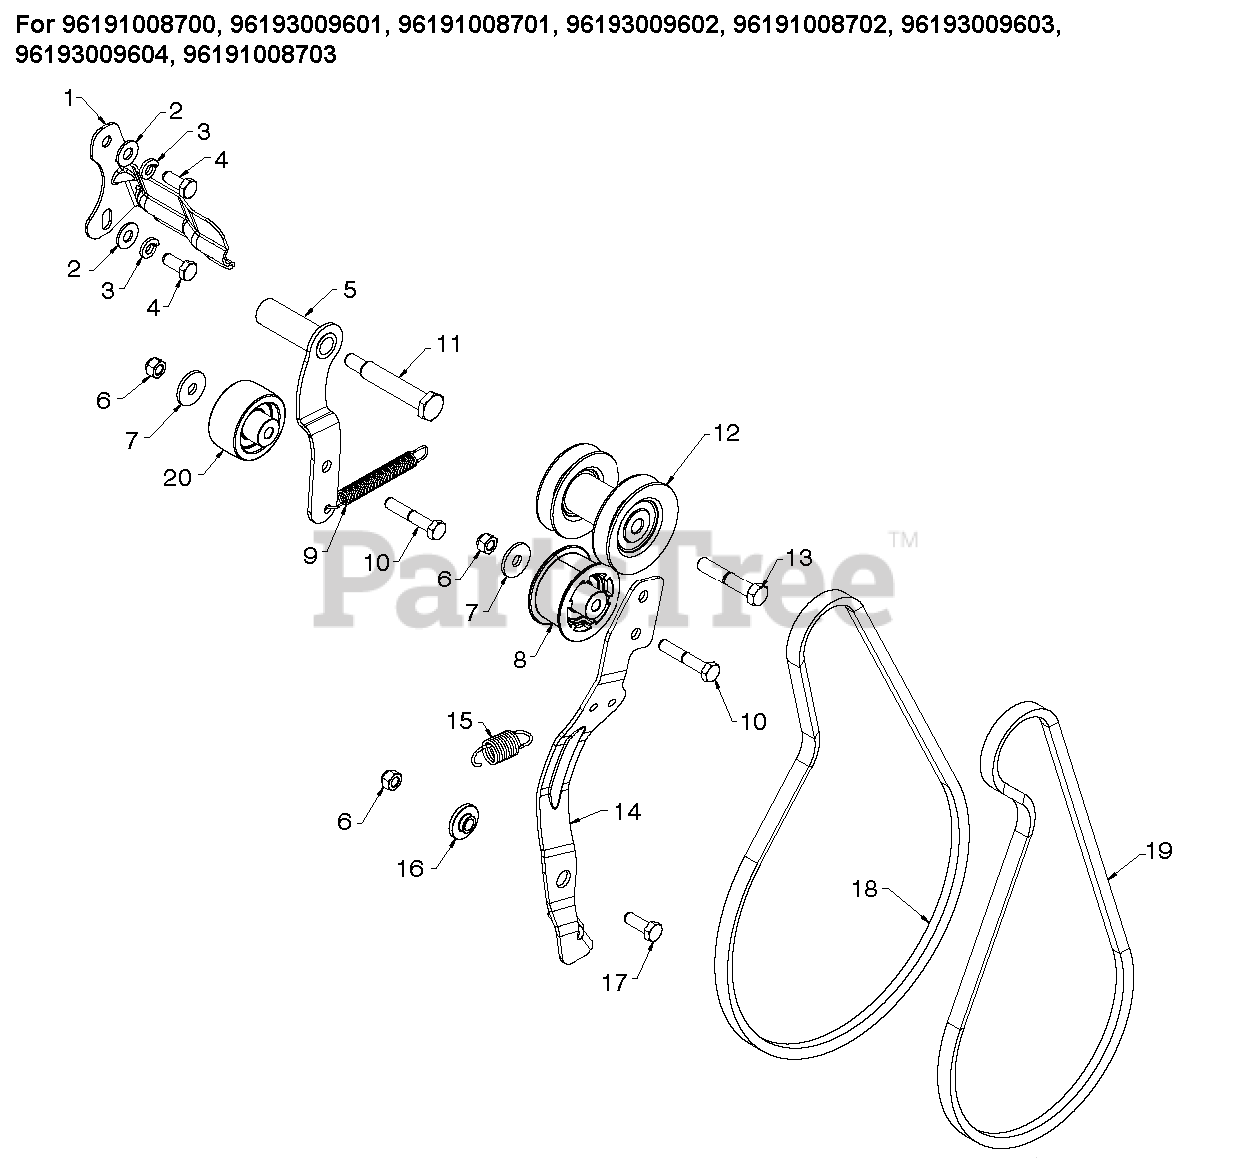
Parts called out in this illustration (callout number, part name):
1	BRACKET.BELT.KEEPER.004.BZP
1	BELT KEEPER BRACKET
2	WASHER M
3	WASHER.LOCK.HVY.HLCL.SPR.5/16
4	SCREW 5/16-24 X .75 GR5
5	ARM IDLER DRIVE WELDMENT_HOT
6	NUT.71038.31-18.HEX.NYLOCK
7	STEEL WASHER
8	PULLEY,IDLER,2.00 W SPA
9	SPRING RETURN IDLER ARM
10	BOLT, HEX 5/16-18X1-3/4
11	BOLT 5/16-24X2.25 HEX HEAD SHO
12	PULLEY.ASM.IMPELLER/DRIVE
13	BOLT.BLADE
13	BOLT.HD.HEAD.3/8-24X2.50 (2 2)
13	BOLT.ENGINE.PULLEY
14	ARM.IDLER.SNOW.BLACK
14	ARM.IDLER.AUTO-PH.676
15	SPRING RETURN, IDLER ARM, IMPE
16	BUSHING.BRAKE.ARM
17	BOLT
18	BELT.DRIVE.SNOW.DUAL
19	LOW CRANK IMPELLER BELT
20	PULLEY.IDLER.FLANG.2.O/SPACER
